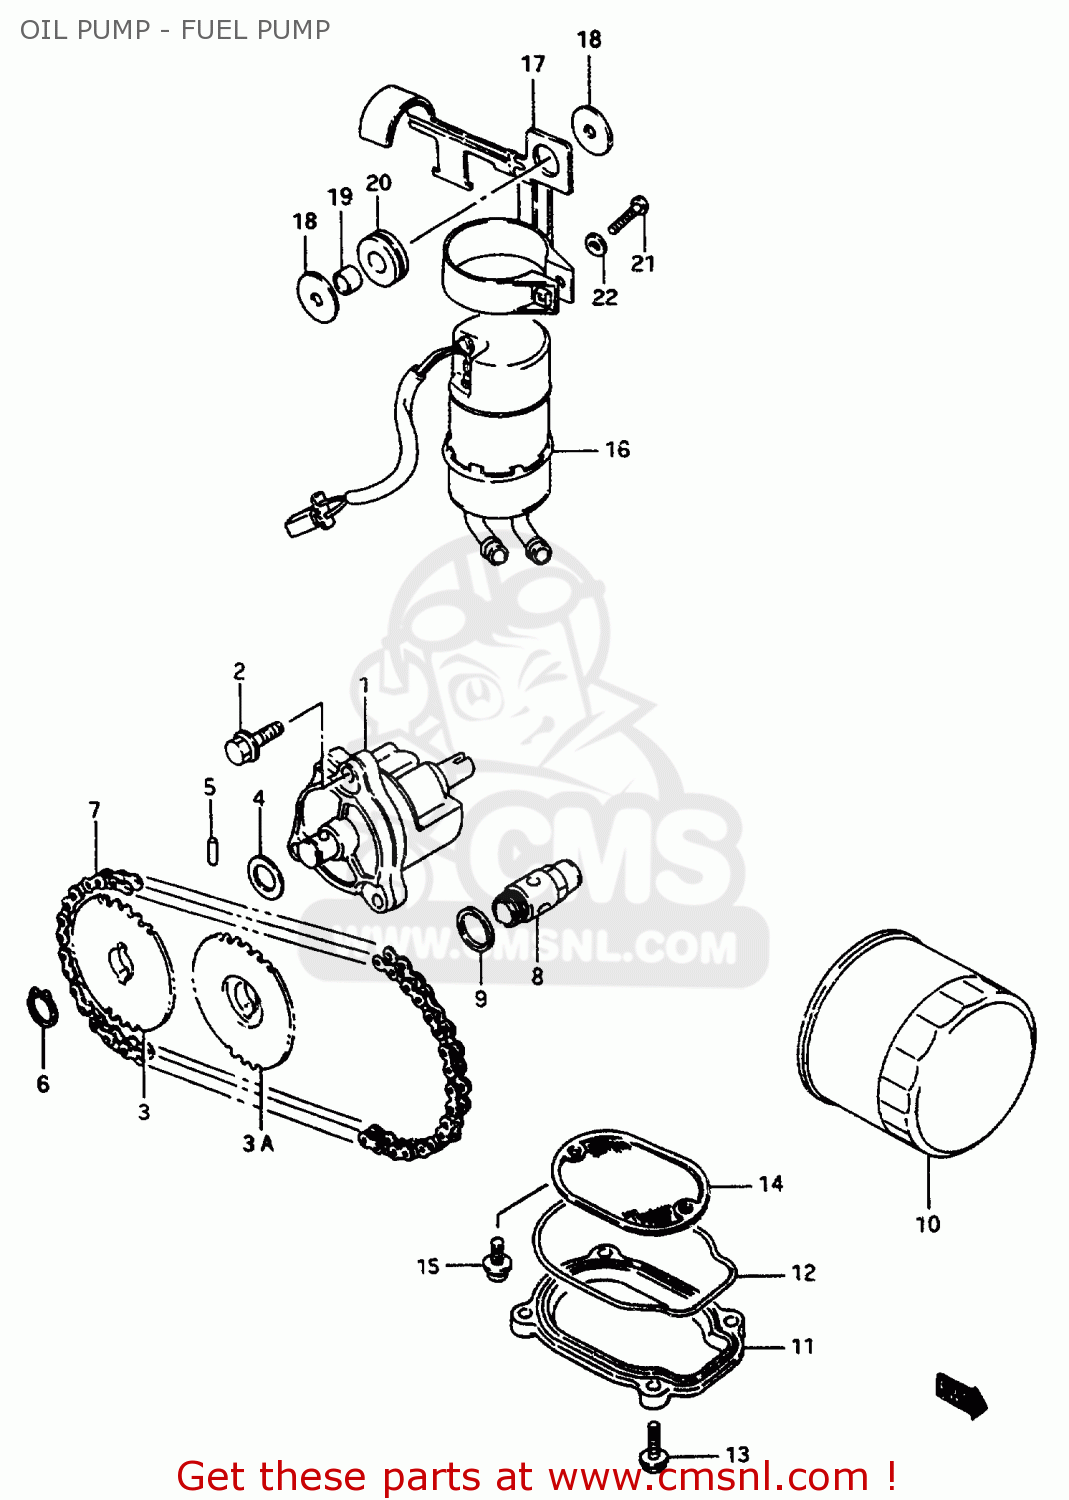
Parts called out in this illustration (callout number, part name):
1	PUMP ASSY,ENGINE OIL
2	BOLT
3	SPROCKET,OIL PUMP DRIVEN
3A	SPROCKET,OIL PUMP DRIVEN
4	SHIM
5	PIN(5X18)
6	CIRCLIP,12 MM
7	CHAIN,OIL PUMP DRIVE
8	VALVE ASSY,OIL RELIEF
9	GASKET(16X22X2) (NAS)
10	FILTER ASSEMBLY,ENGINE OIL
11	CAP,OIL STRAINER
12	O RING,OIL STRAINER CAP
13	BOLT
14	STRAINER,ENGINE OIL
15	SCREW
16	PUMP ASSY,FUEL
17	BRACKET,FUEL PUMP
18	WASHER (6.5X24X1.6)
19	SPACER(6.5X10.5X6.5)
20	CUSHION
21	SCREW
22	WASHER
